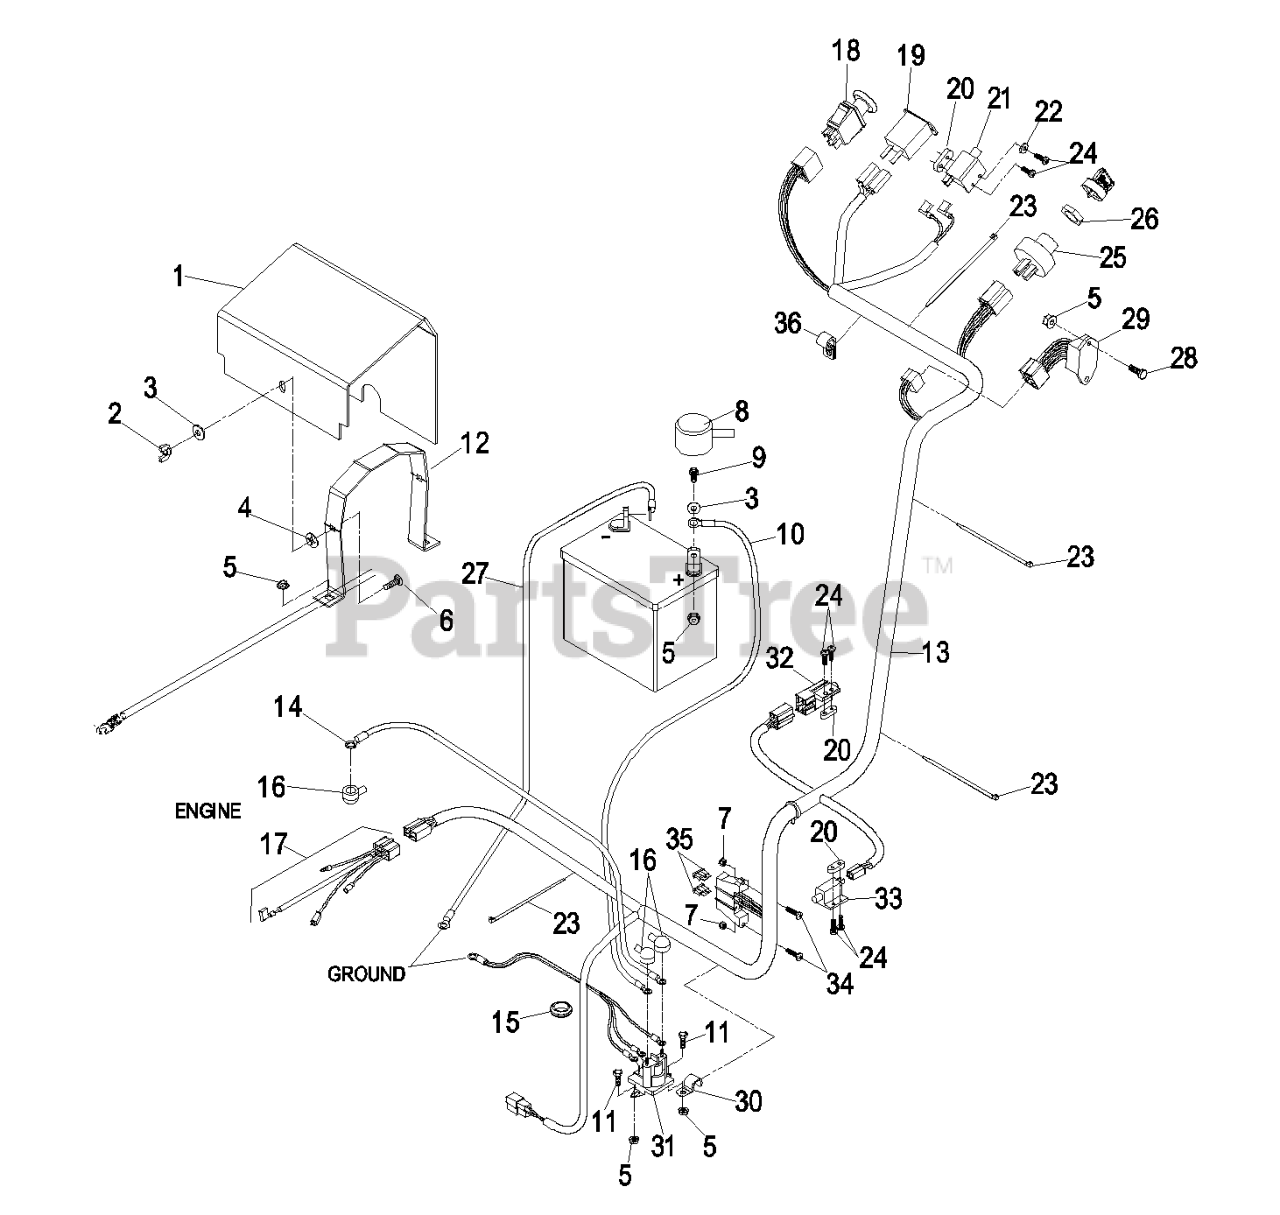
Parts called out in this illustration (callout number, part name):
1	COVER,BATTERY W/DECAL
2	NUT-WING
3	WASHER-FLAT
4	NUT-RETAINING
6	BOLT-CARR
7	NUT-LOCK, NI
8	INSULATOR-BATTERY
9	SCREW-HH
10	POSITIVE BATTERY CABLE AS
11	SCREW-HH
12	STRAP,BATTERY HOLDDOWN
13	HARNESS,TT PG WIRING
14	ASM,POSITIVE STARTER CABL
15	GROMMET
16	INSULATOR-SOLENOID
17	HARNESS,WIRING 19KA
18	SWITCH-PTO
19	METER-HOUR
20	PLATE-TAPPED
21	SWITCH-OPEN, NORMALLY
22	WASHER-FLAT
23	TIE-PLASTIC
24	SCREW-PPH
25	SWITCH,IGNITION
26	NUT-SWITCH, IGNITION
27	WIRE-GROUND
28	SCREW-HH
29	MODULE-OPC NO TIME DELAY
30	CLIP-HALF, LOOM
33	SWITCH-CLOSED, NORMALLY
34	SCREW-HEAD, TRUSS
35	FUSE-BLADE TYPE, 20 AMP
36	CLIP-LOOM
